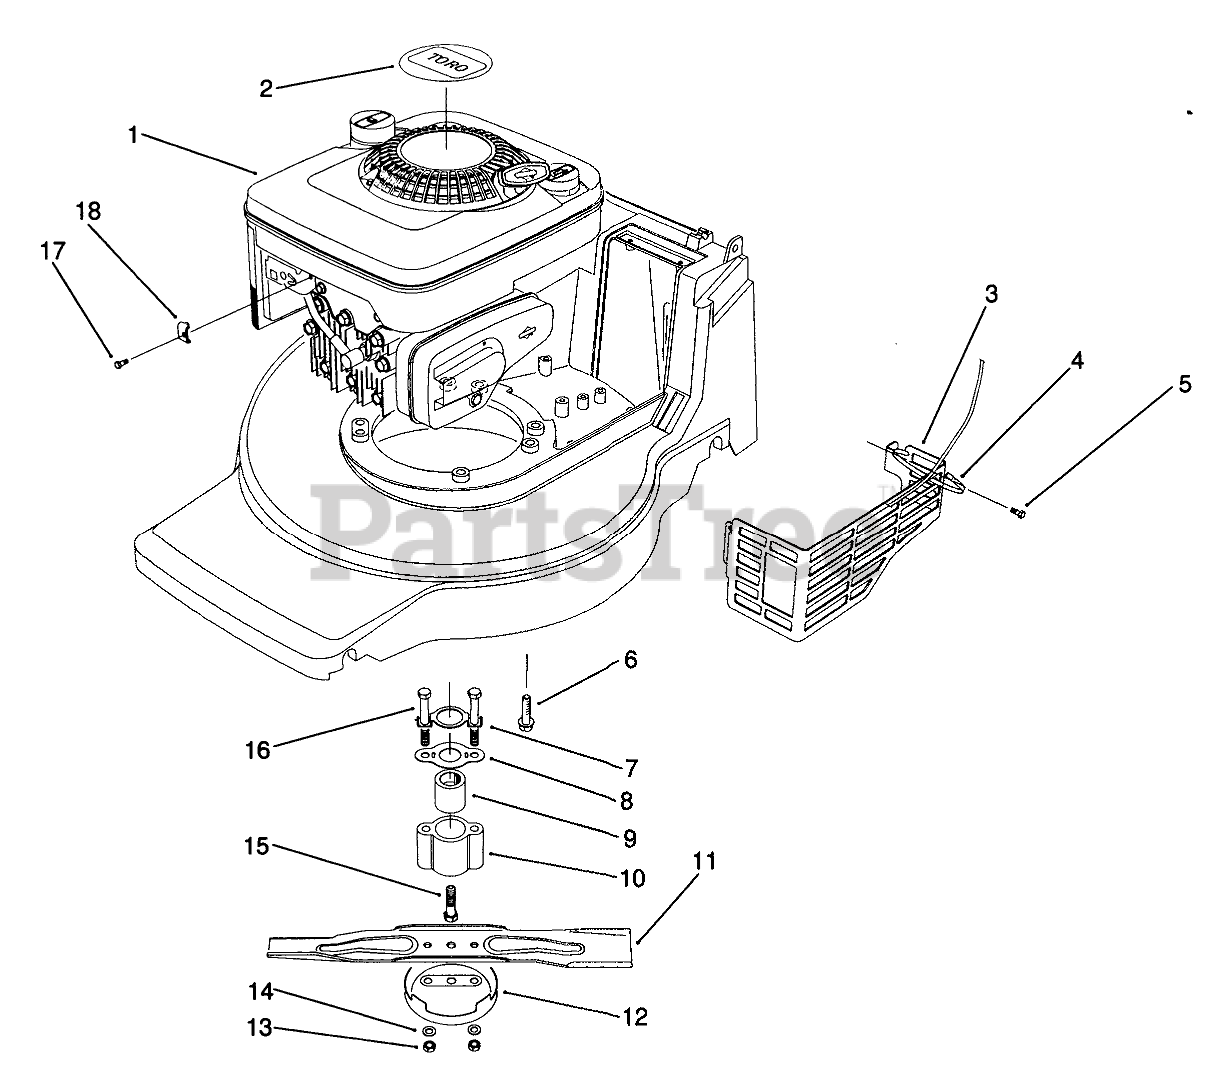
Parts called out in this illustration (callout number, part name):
1	Quantum
2	DECAL - RECOIL
3	SHIELD-MUFFLER
4	TIE-CABLE
5	SCREW-HWH
6	3/8-16 X 2 CAPSCREW
7	BLADE RETAINER BRKT
8	SPRING FRICTION
10	RETAINER
11	Blade-48cm
12	Anti Scalp Cup
13	Nut
14	WASHER
15	SCREW - CRANKSHAFT
16	SCREW - BLADE
17	Screw
18	CLAMP-CASING
